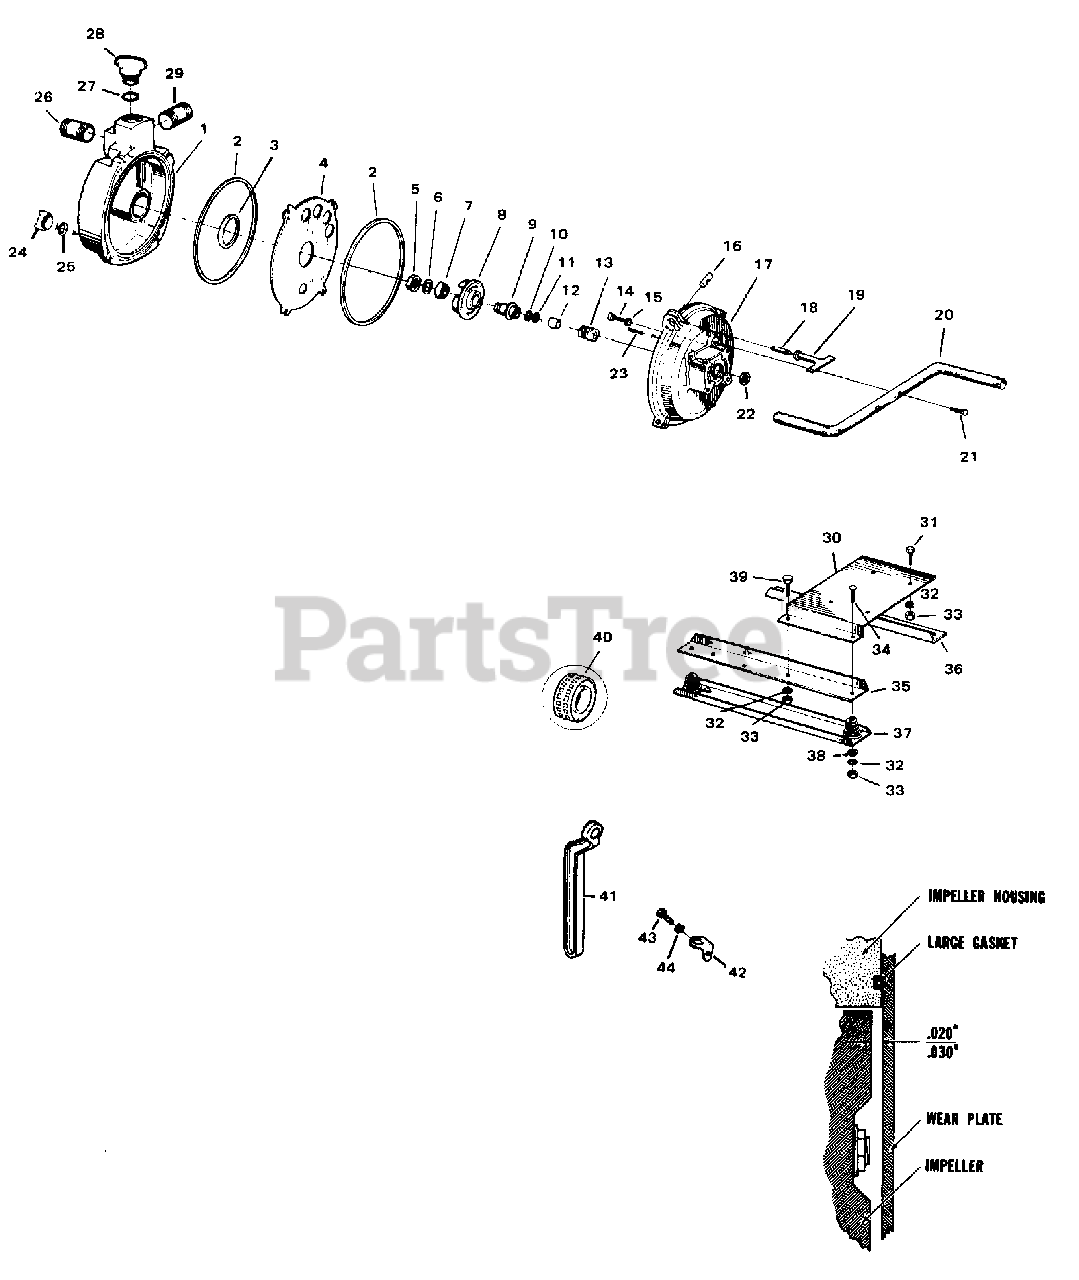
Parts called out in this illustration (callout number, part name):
1	HOUSING- End
2	GASKET- Large
3	GASKET- Small
4	PLATE- Wear
5	NUT
7	BUSHING- Tapered
8	IMPELLER
9	HUB- Impeller
10	SHIM,.010
11	SHIM,.015
12	SPACER- Crankshaft
13	SEAL ASSEMBLY
14	SCREW- Hex hd., 5/16-24 x 2 1/4
15	WASHER- Sealing
16	PIVOT- Handle
17	HOUSING- Impeller
18	STUD- Handle
19	HANDLE- Disconnect
20	HANDLE- Carrying
21	SCREW- Hex hd., 5/16-18 x 1 1/4
22	SLINGER
23	PIN- Spirol
24	PLUG- Drain
26	NIPPLE, 2" x 2" long
28	PLUG- Wing
29	NIPPLE, 2" x 3 1/2" long
30	PLATE- Engine mounting
31	SCREW, 5/16-18 x 1 1/2
32	WASHER- Lock, 5/16
33	NUT, 5/16-18
34	BOLT- Carriage, 5/16-18
35	ANGLE- Base, left side
36	ANGLE- Base, right side
37	SKID ASSEMBLY
38	WASHER- Flat, 5/16
39	SCREW, 5/16-18 x 3/4
40	STRAINER
41	WRENCH- Spanner
42	HOLDER- Spanner wrench
43	SCREW- Fil, hd. 1/4-20 x 3/8
44	WASHER- Flat, 1/4
